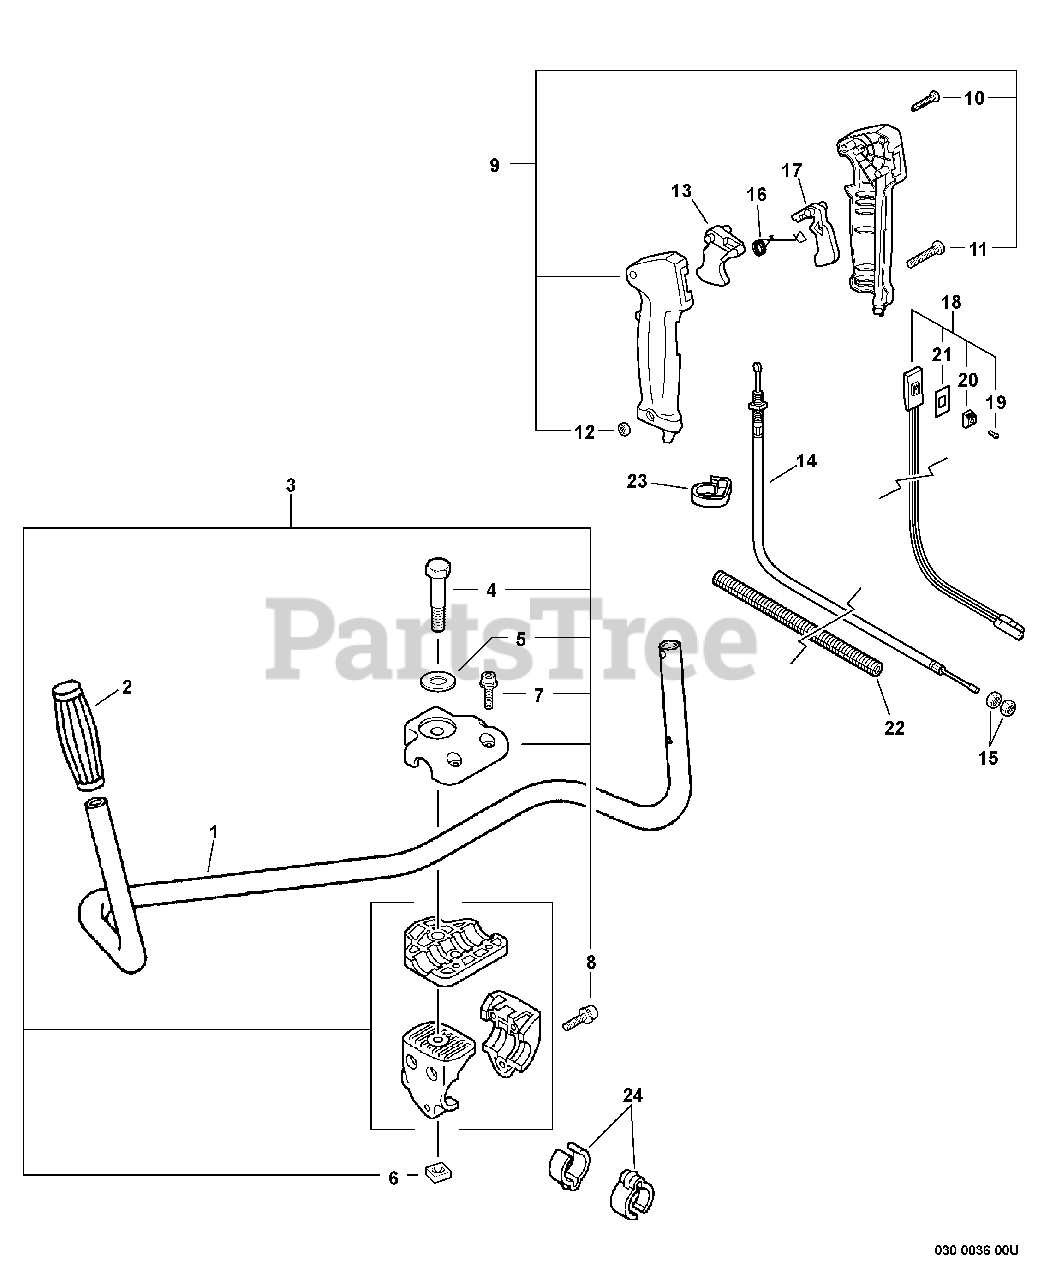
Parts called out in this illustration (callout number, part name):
1	HANDLEBAR
2	GRIP, HANDLE
3	BRACKET KIT, HANDLEBAR
4	BOLT 8×55
5	WASHER 8
6	NUT 8×1.25
7	BOLT 5×20
8	BOLT 5×30
9	CONTROL HANDLE KIT
10	SCREW 3×25
11	SCREW 5×30
12	NUT M5
13	TRIGGER, THROTTLE
14	CABLE, THROTTLE
16	SPRING, TORSION
17	LOCKOUT, THROTTLE
18	SWITCH, ON-OFF
19	SCREW 3×10
20	KNOB, SWITCH - ORANGE
21	LABEL, SWITCH
22	TUBE, FLEXIBLE 7×790
24	CLIP, CABLE 25 MM
